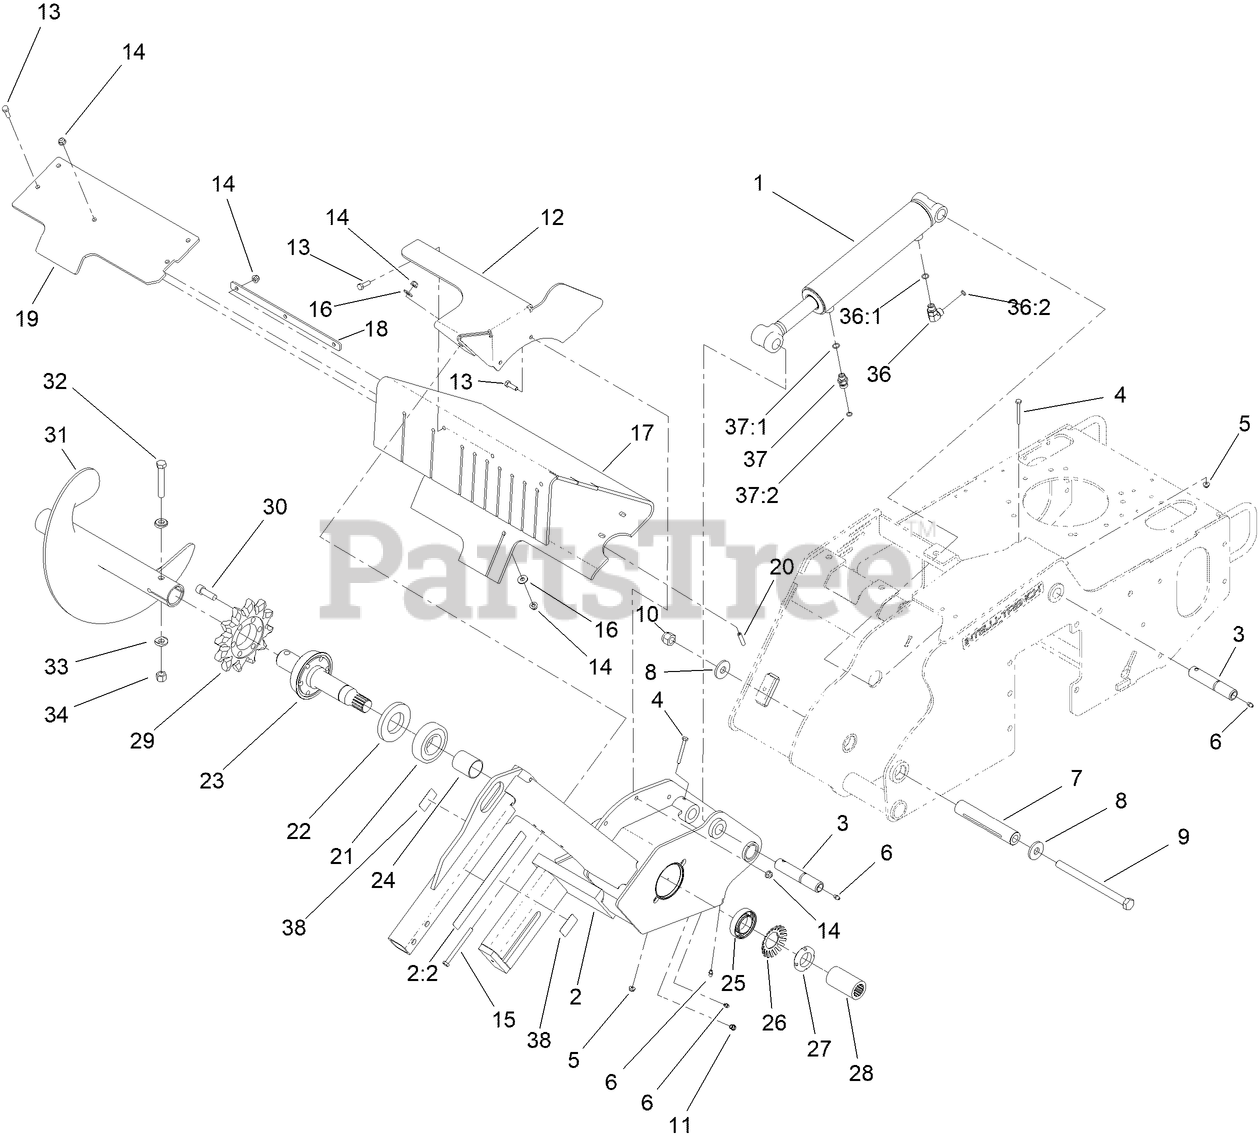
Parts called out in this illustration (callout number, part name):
1	HYDRAULIC CYLINDER ASM
2	TRENCHER HEAD ASM
2:2	DECAL-DANGER
3	PIN-PIVOT
4	SCREW-HH
5	NUT-HF
6	FITTING-GREASE
7	SPACER-PIVOT
8	WASHER-HARDENED
9	BOLT-HH
10	NUT-LOCK, NI
11	FITTING-LUBE
12	BRACKET-SHIELD
13	SCREW-HH
14	NUT-HF, NI
15	SCREW-HH
16	WASHER-FLAT
17	SHIELD-DIRT
18	PLATE-STRAP,SHIELD
19	BAR-CLAMP
20	SCREW-HSH
21	BEARING-BALL
22	SEAL-GREASE
23	SHAFT-TRENCHER
24	SPACER
25	BEARING-BALL
26	LOCKWASHER-BEARING
27	LOCKNUT-BEARING
28	COLLAR-SPLINED
29	SPROCKET-TRENCHER
30	SCREW-HSH
31	TRENCHER AUGER ASM (WELDED)
32	SCREW-HH
33	WASHER-SADDLE
34	NUT-LOCK, NI
36	FITTING-ELBOW, 90 DEG
36:1	O-RING
36:2	O-RING
37	VALVE-CHECK
37:1	O-RING
37:2	O-RING
38	DECAL-LIFT, TIE DOWN
